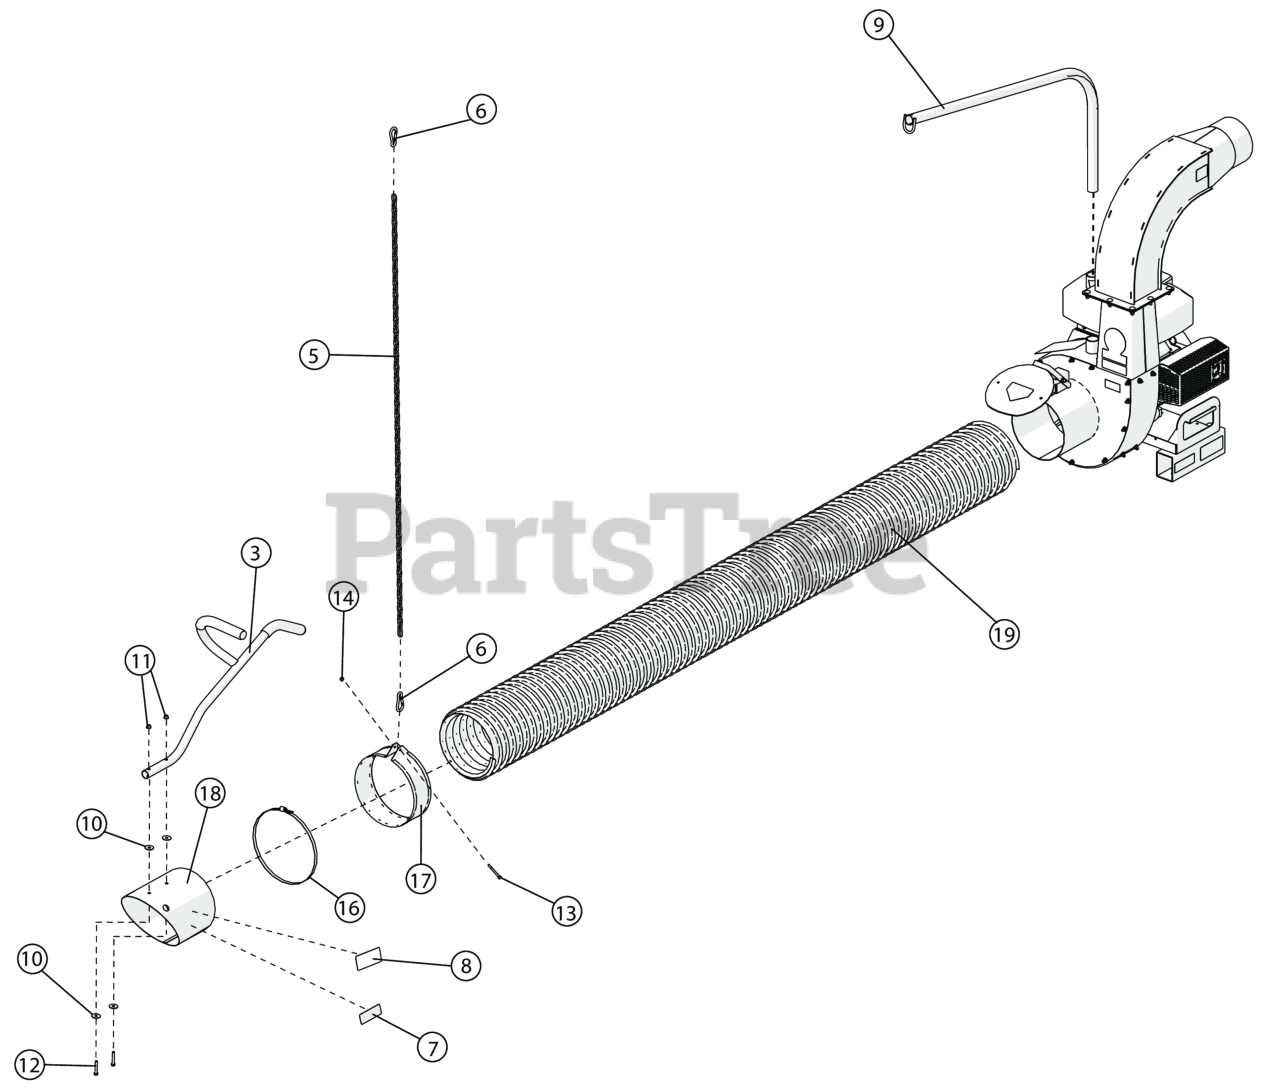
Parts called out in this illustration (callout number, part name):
3	SEE: 791116-S
5	CHAIN 73 LINKS DL
6	HOOK, SNAP SAFETY 5/16" ZP
7	LABEL WARNING HOSE TRAY QL23
8	LABEL WARNING ENGINE OVERHEAT
9	BOOM WA DL
10	WASHER FLAT FENDER 5/16
11	NUT-HEX-NYLK, FLG .3125-18 ZP
12	SCREWCAP 5/16"-18X2" HCS ZP
13	SCREWCAP 1/4"-20X2 3/4" HCS ZP
14	NUT-HEX-NYLK, FLG .250"-20 ZP
16	CLAMP HOSE 10"
17	BAND HOSE BOOM 10" FORMED
18	SEE: 811005-S
19	HOSE INTAKE 10"X 10' (SEE ACCESSORY PRICELIST ITEM 791033-S)
